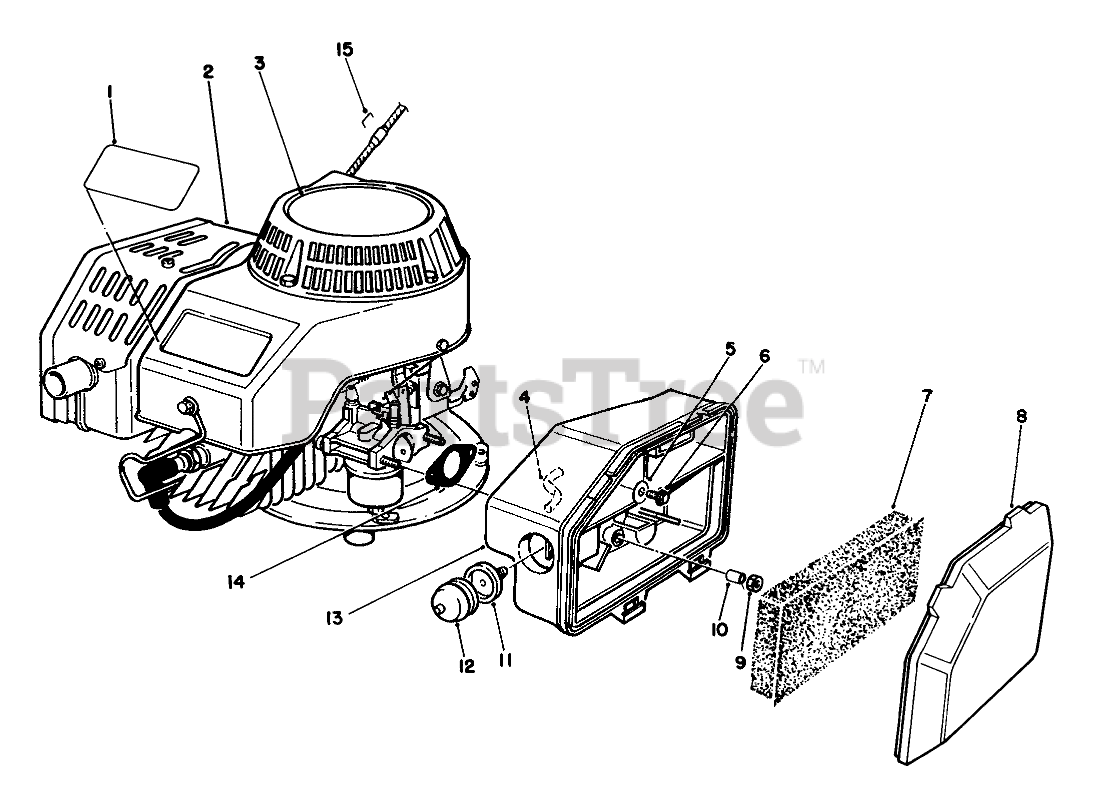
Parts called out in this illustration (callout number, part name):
1	DECAL - PROLINE
2	ENGINE ASM
3	DECAL-2 CYC RECOIL COMM
4	HOSE-PRIMER
5	WASHER-FLAT
6	SCREW-HH
7	ELEMENT-AIR CLEANER
8	COVER-AIR CLEANER
10	SPACER
11	BODY-PRIMER
12	BULB-PRIMER
13	BODY-AIR CLEANER
14	GASKET-AIR CLEANER
15	Staple
